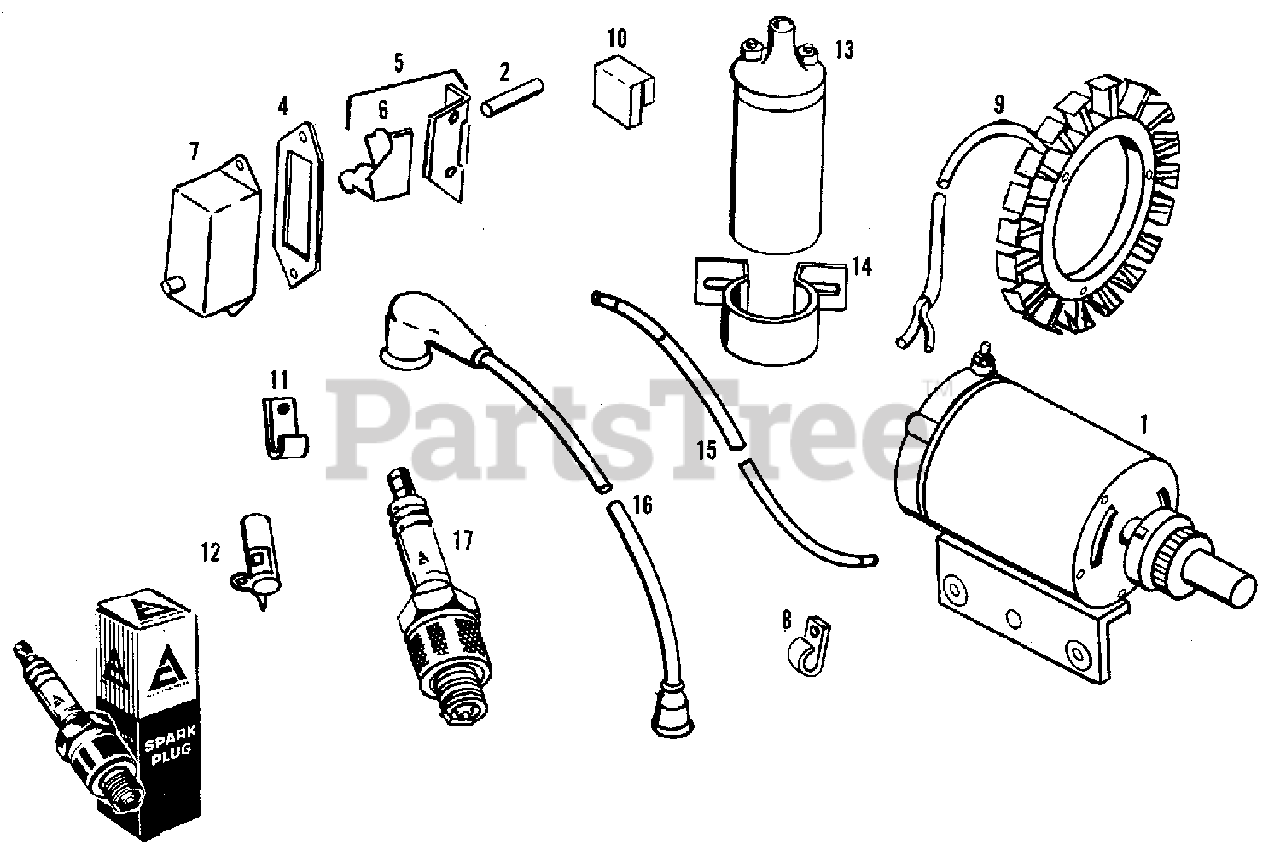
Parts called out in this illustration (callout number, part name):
1	STARTER ASSEMBLY, (Includes Item 2 & 3)
1	KIT, Brush and Spring
1	KIT, Starter Drive (Includes Item 2066445 & 2066446)
1	SPRING, Anti-Drift
1	SPACER, Gear Stop
1	KIT, Starter Drive (Model 416H)
2	ROD, Breaker
5	BREAKER ASSEMBLY
6	POINT ASSEMBLY, Breaker
10	CONNECTOR
11	CLIP, Cable
12	CONNECTOR
15	LEAD, Breaker
16	CABLE, High Tension
17	PLUG, Spark
